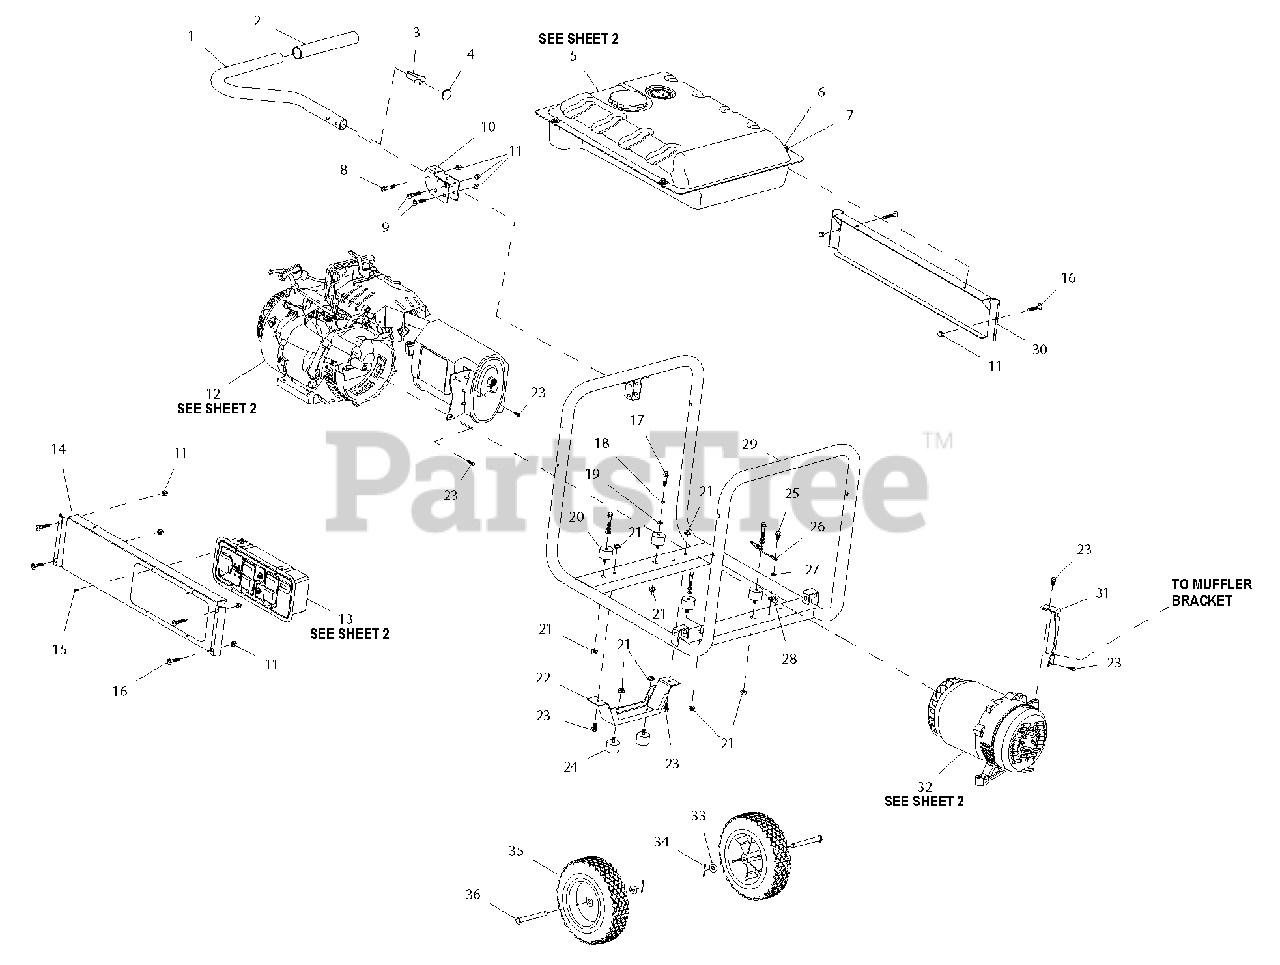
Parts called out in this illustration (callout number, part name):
1	HANDLE GP
2	HANDLE GRIP GP
3	SNAP BUTTON - .437" DIA. HEAD
4	CAP, END NYLON BLACK
5	FUEL TANK ASSEMBLY 7.2 GAL CARB
6	RUBBER MOUNT,10.3 ID X 11 HGT
7	INSERT, ANTI-CRUSH FOR TANKS
8	SCREW HHFC M8-1.25 X 45 G8.8
9	CHB M8-1.25 X 46MM LONG
10	HANDLE BRACKET GP
11	CAP NUT M8-1.25 BLACK ZINC
12	ASSY ENGINE 389 CATALYST
13	CONTROL PANEL ASSEMBLY
14	PANEL RAIL C/PNL SIDE GP
15	SCREW PPPH #8-16 X .66" BZC
16	CURVED HEAD M8-1.25 X 41MM LNG
17	SCREW HHC M8-1.25 X 35 C8.8
18	WASHER LOCK M8-5/16
19	WASHER FLAT 5/16-M8 ZINC
20	VIB MNT 35MM X 25.4 X M8-1.25
21	NUT HEX FL WHIZ M8-1.25
22	FOOT, BENT, GP5000-GP8000
23	SCREW HHFC M8-1.25 X 16 G8.8
24	VIB MNT 38.1 X 25.4 X M8-1.25
25	SCREW HHFC M6-1.0 X 16 G8.8
26	WIRE ASSY GND ALT TO BASE
27	WASHER LOCK SPECIAL 1/4"
28	LUG, SOLDERLESS #2-#8
29	ASSEMBLY FRAME GP5-6.5KW CARB
30	PANEL RAIL BACK GP
31	BRACKET, MUFFLER 389CC
32	ALTERNATOR, GP CARB
33	WASHER FLAT 1/2 ZINC
34	PIN COTTER 1/8 X 1-1/4 ZN PLT
35	WHEEL, INCH 9.5 DIA, PLASTIC
36	AXLE PIN, 1/2"X 4", 3/4" HEAD
